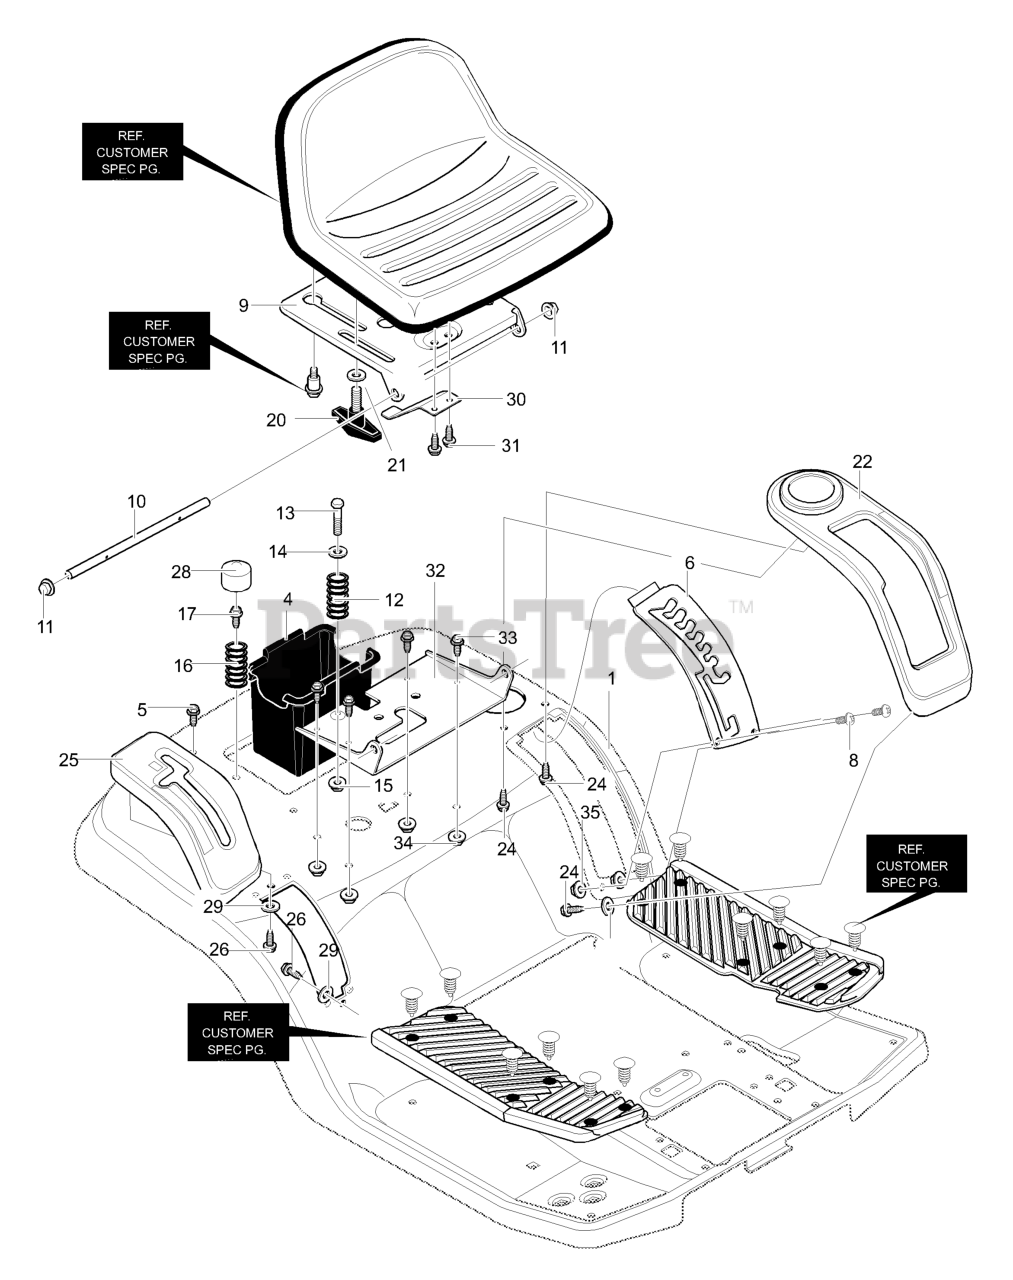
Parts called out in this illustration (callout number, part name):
1	Seat Deck
4	Battery Container
5	Screw, 1/4-20x.63
6	Plate, Lift Detent
8	Screw, 10-24x.500
9	Seat Support
10	Hinge Seat Pivot
11	Push Cap Nut
12	Comp. Spring
13	Shoulder Bolt, 1/4-20
14	Washer Cup
15	Nut, 1/4-20
16	Comp. Spring
17	Screw, 5/16-18 x 0.75
20	Wing Bolt 5/16-18x.50
21	Washer
22	Detent Cover w/cup
24	Screw, 1/4-15
25	Shift Cover Hand/Foot
26	Screw, 1/4-15x.44
27	Flat washer
29	Flat washer
30	Spring - Leaf
31	Screw, 1/4-20x.50
32	Bracket, Pivot Seat
33	Screw, 5/16-18 x 0.75
34	Nut, 5/16-18 Wdfllk
35	Nut, #10-24 Locknut
